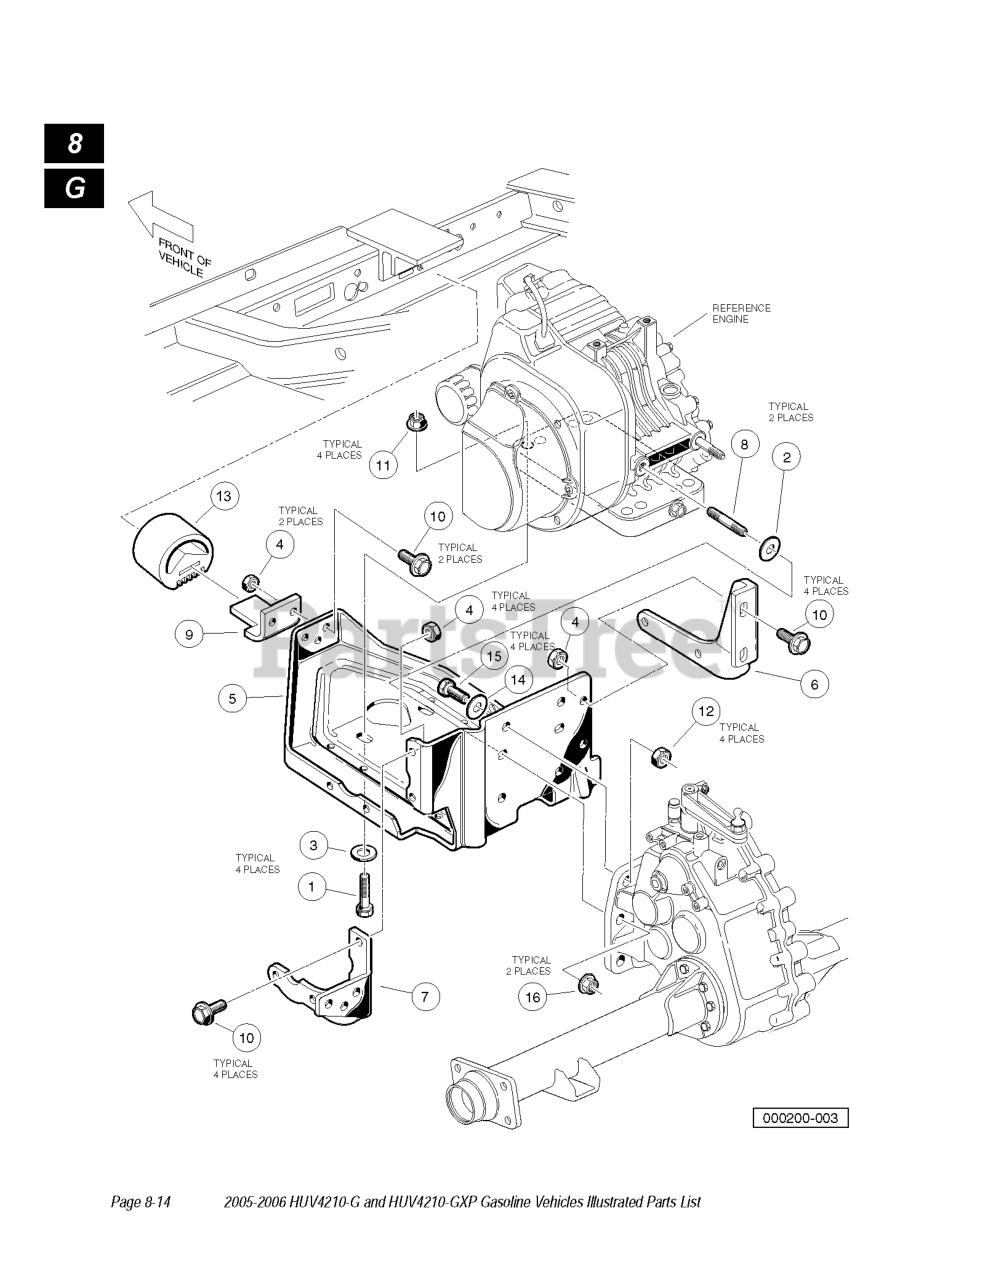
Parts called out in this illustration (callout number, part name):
1	BOLT HEX HEAD
2	WASHER, 5/16 FLAT
5	PLATE, ENGINE MOUNTING
6	PTO SIDE STIFFENER
7	STIFFENER, FLYWHEEL SIDE
8	STUD, M8-1.25 X 50MM 2-ENDED
9	SNUBBER BRACKET
10	SCREW, 5/16-24 X .875 GR8 FLNG
11	LOCKNUT, 5/16-18 HEX FLANGE
12	LOCKNUT, 3/8-16 FLANGED DIMPLE
13	INNER FRAME SNUBBER
14	WASHER, 3/8 FLAT
16	NUT, M8-1.25 FLANGED HEX
